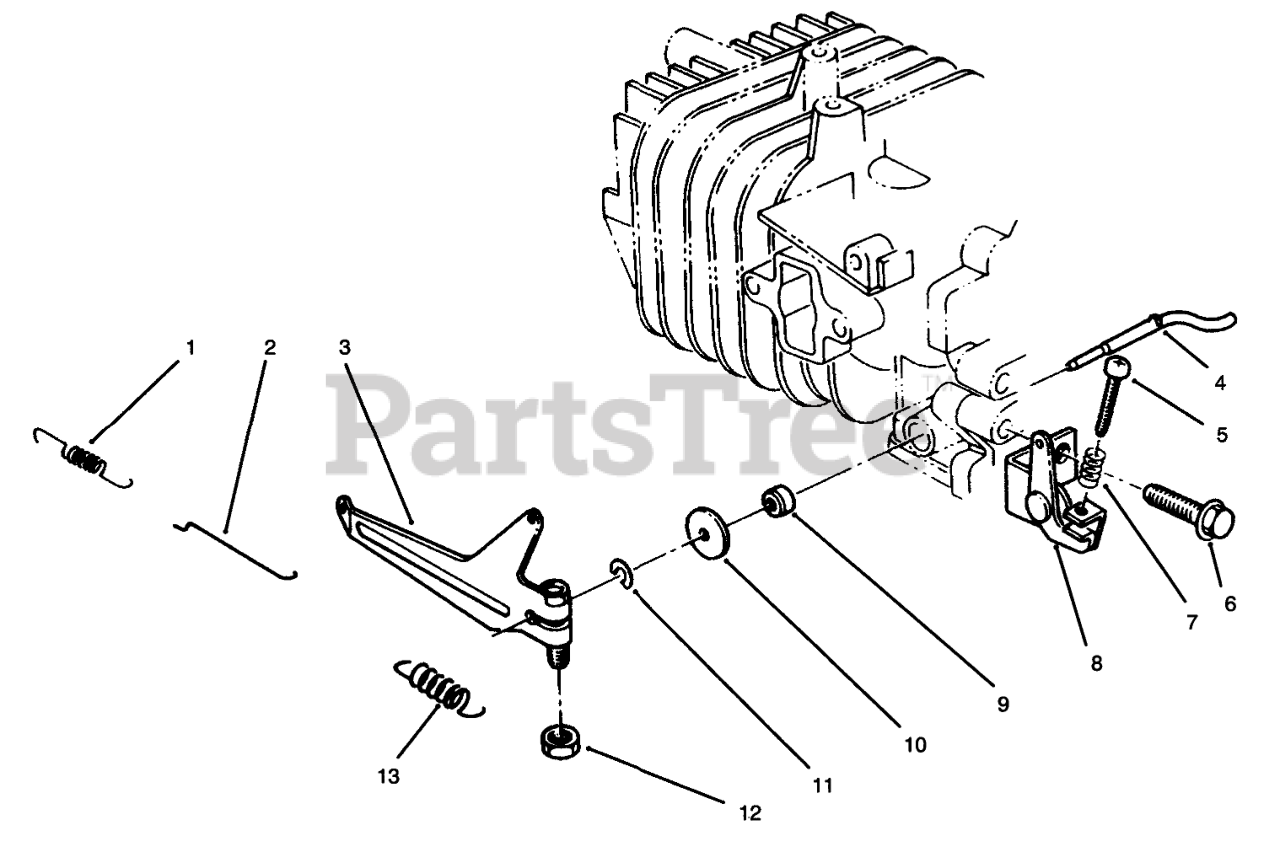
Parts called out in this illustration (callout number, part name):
1	CARB SPRING
2	CARB ROD
3	GOVERNOR ARM
4	SHAFT
5	SCREW
7	SPRING
8	GOV SPR BRKT
9	SEAL-OIL
10	WASHER
11	E-RING
13	GOV SPRING
